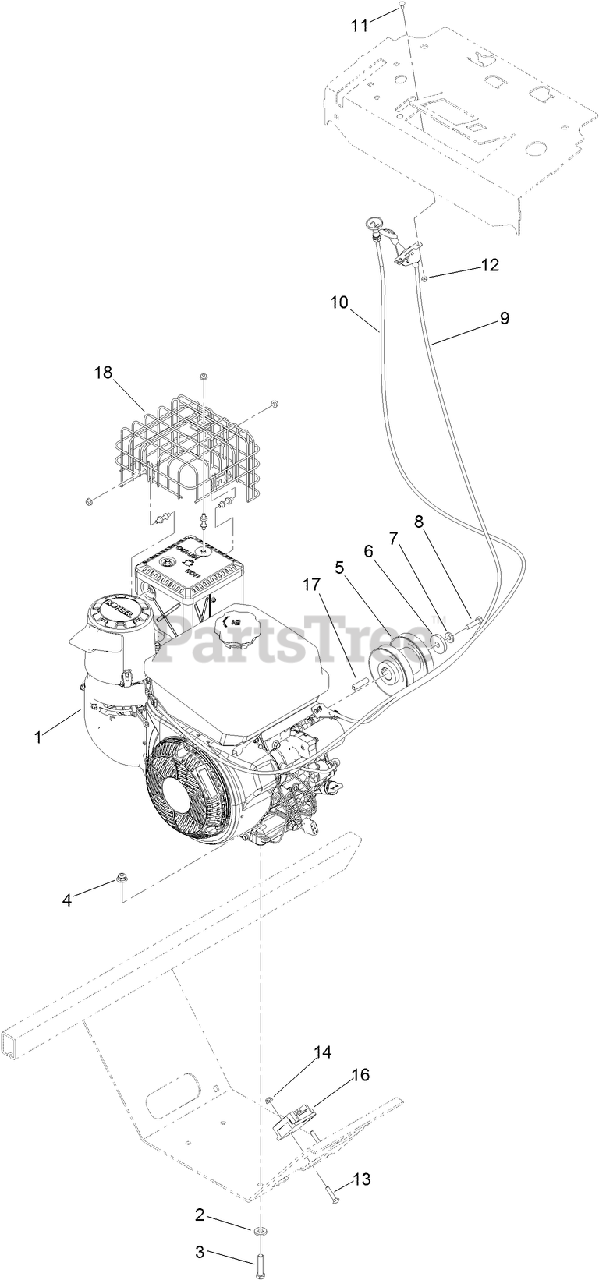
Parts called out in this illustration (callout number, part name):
1	ENGINE-KOHLER, CH440-3041
2	WASHER-BELLEVILLE
3	SCREW-HH
4	NUT-HF, NI
5	PULLEY
6	WASHER-CLUTCH
7	WASHER-SPRING
8	SCREW-HH
9	CONTROL-THROTTLE
10	CABLE-CHOKE, PUSH/PULL
11	BOLT-CARR
12	NUT-LOCK, NI
13	SCREW-CARR
14	NUT-HF
16	REGULATOR
17	KEY-SQUARE, 7MM
18	KIT-MUFFLER BIRDCAGE
